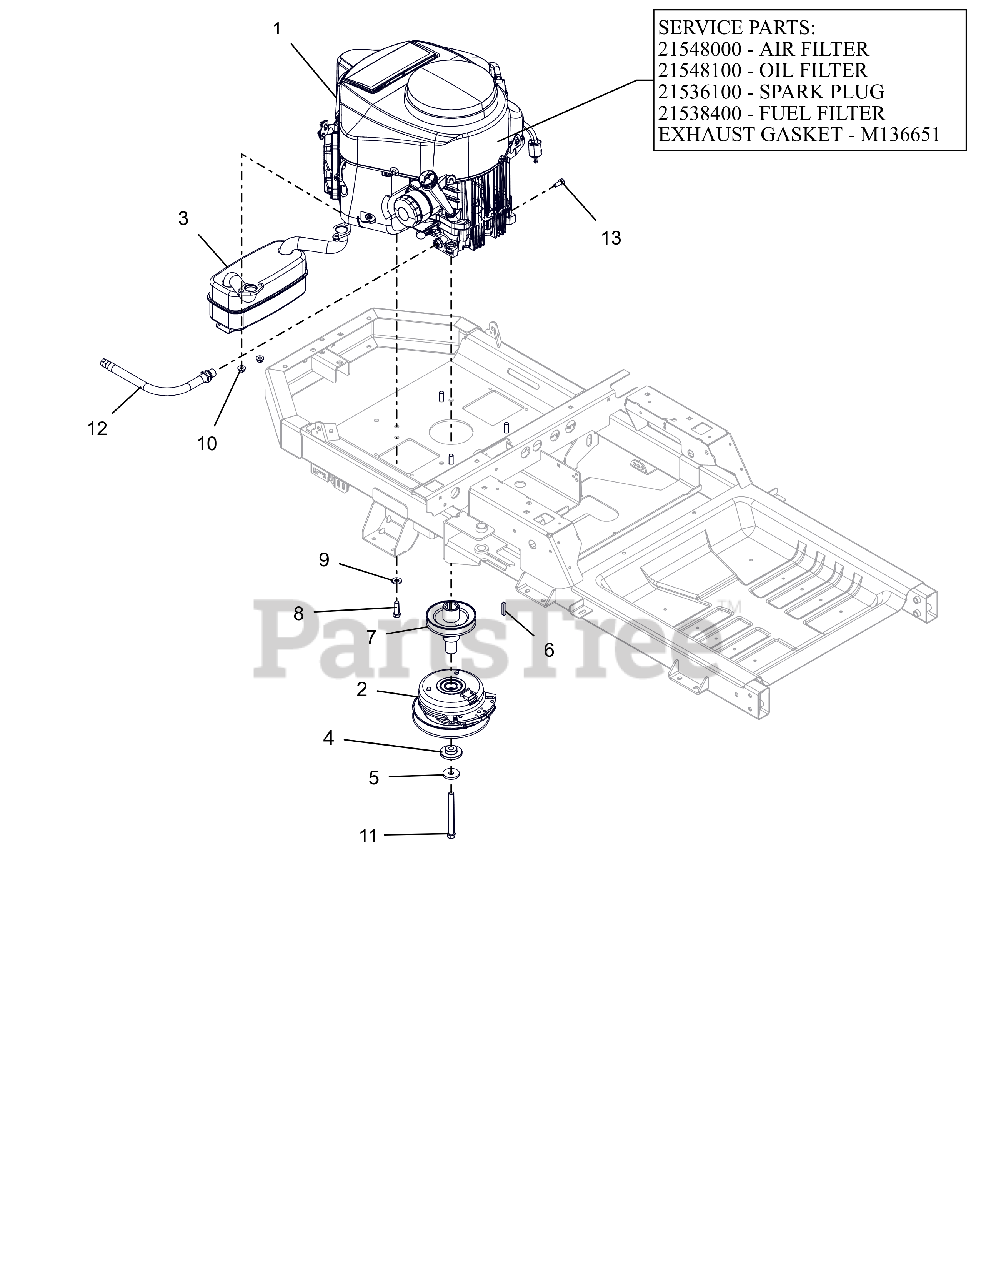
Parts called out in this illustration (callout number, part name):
1	ENGINE, KAWASAKI FR651V 22HP
1	AIR FILTER, KAWASAKI FR
1	OIL FILTER, KAWASAKI FR
1	PLUG, SPARK
1	FUEL FILTER - KAWASAKI
1	GASKET, MUFFLER #
2	CLUTCH,105FTLB MONOPOLE 6.83"
3	MUFFLER, KAWASAKI
4	BSHG-FLG .469X1.06X.574X2.0
5	WASHER, 7/16" SPRING DISK
6	KEY-SQ .25 X 1.25 X .25 SAE
7	WLDMT, DRIVE SHEAVE-X
8	BLT, HEX .38-16X1.25 G5 ZCC NT
9	WASHER, 3/8" SPRING DISC
10	NUT-LK-TOP-FLG M8 ZCC
11	BLT, HEX .44-20X4.50 G8 ZCC NT
12	HOSE, OIL DRAIN
13	BLT, HEX M8-1.25X20 G8.8 ZCC
